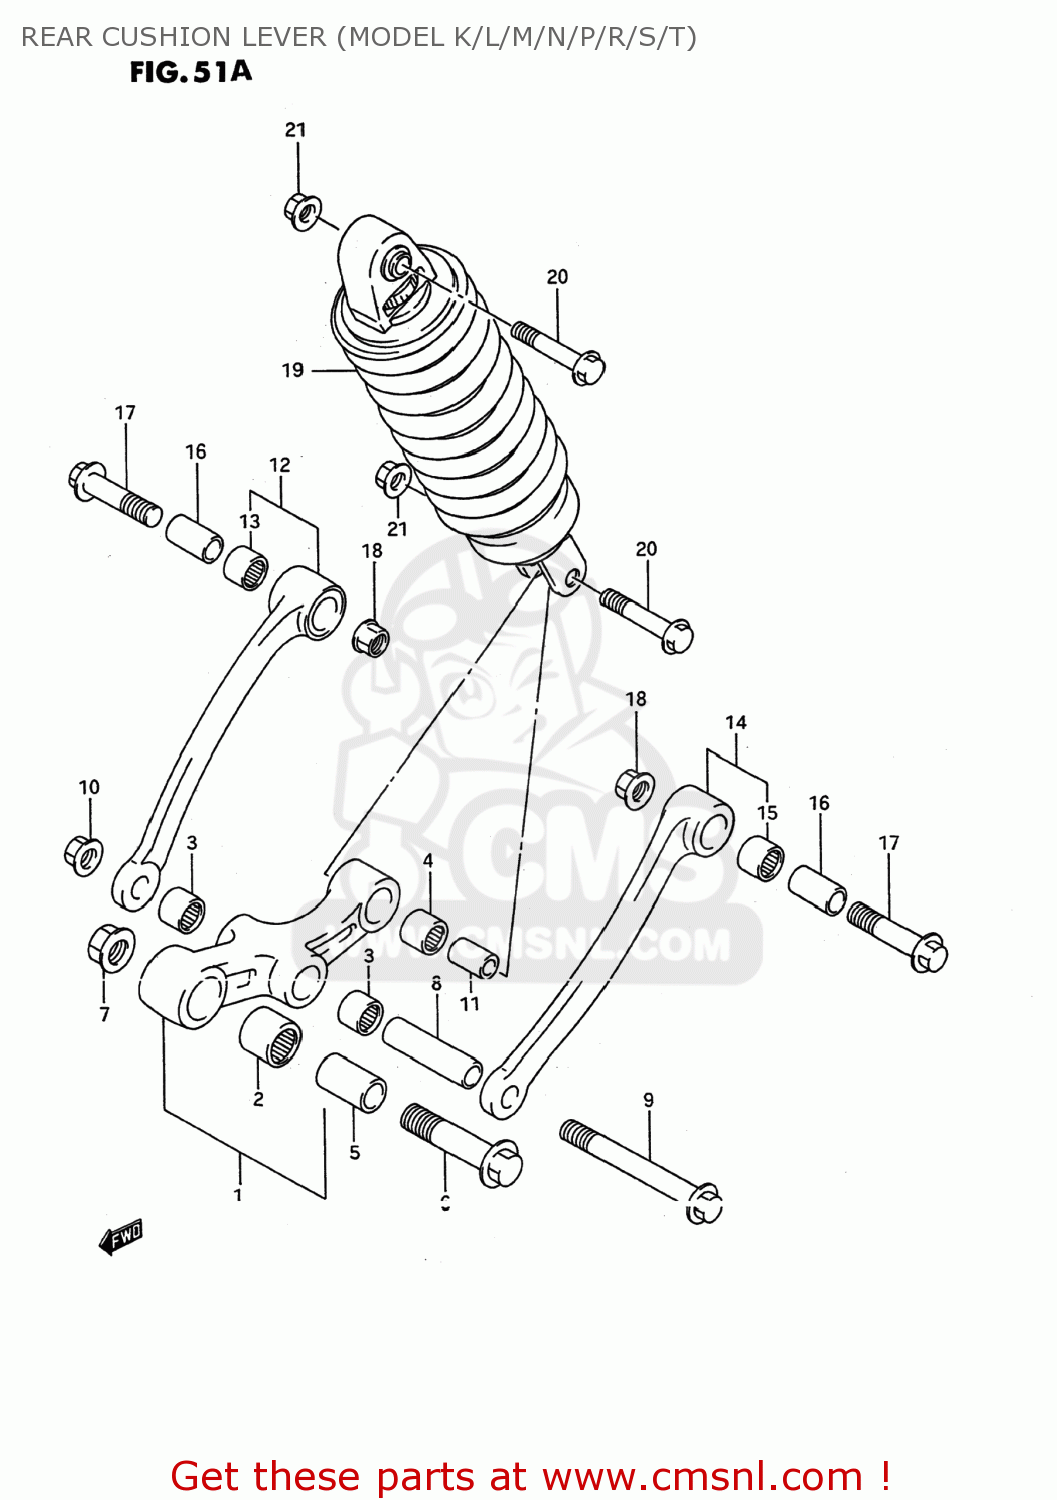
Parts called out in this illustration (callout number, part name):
1	LEVER SET,RR CUSHION
2	BEARING(20X27X30)
3	BEARING(17X24X25)
4	BEARING(17X24X26)
5	SPACER(14X20X34)
6	BOLT(14X62)
7	NUT 14MM
8	SPACER(12X17X60)
9	BOLT(12X96)
10	NUT 12MM
11	SPACER,RR CUSHION LEVER
12	ROD SET,RR CUSHION,R
13	BEARING(17X24X26)
14	ROD SET,RR CUSHION,L
15	BEARING(17X24X26)
16	SPACER(12X17X29)
17	BOLT L:52
18	NUT 12MM
19	ABSORBER ASSY,RR SHOCK
20	BOLT(10X52)
21	NUT 10MM
